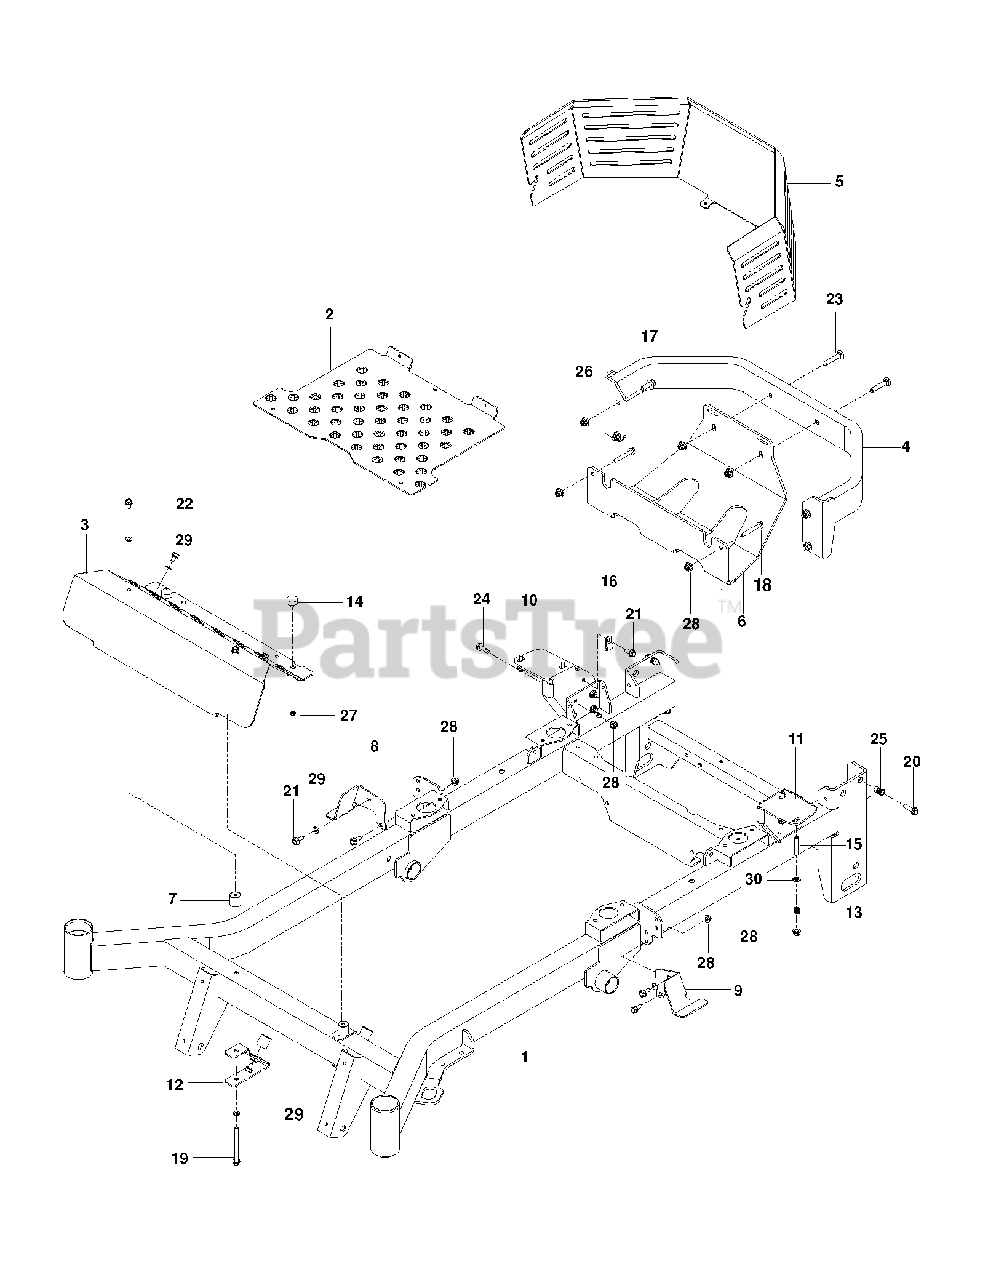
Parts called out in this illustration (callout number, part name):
1	FRAME W/DECALS, GARIZZLY SE
2	PLATE, FLOOR PAN, BLUE
3	PLATE, FOOTREST, BLUE
4	BUMPER, REAR, BLUE
5	GUARD, REAR, BLUE
7	MOUNT, F/F INSERT
10	MOUNT, TANK, RT-BLK
11	MOUNT, TANK, LT-BLK
12	BRACKET, REST MOUNT
14	BUMPER, 1/4-20 STUD, 1/4
15	STUD, 5/16C
16	DOUBLE TUBE CLAMP
17	HHFS 3/8-16 X 1 GRD 5 ZD
18	HHFS 5/16-18 X 2.25 GD 5
19	HHFS 5/16-18 X 3 3/4
20	HHFS 5/16-18 X 1.25 TPBLT GD 5
21	HHFS 5/16-18 X 3/4
22	SCR 5/16-18 X 1/2 SELFTAP ZN
23	RHSNB 3/8C X 2
26	NUT 3/8-16 HEX FLG NYLOC ZD
27	JAM NUT 1/4C
28	5/16-18 NYLOC FLANGE NUT
29	WASH 5/16 DISC SPRING ZD
30	FLAT WASHER 5/16 SAE
